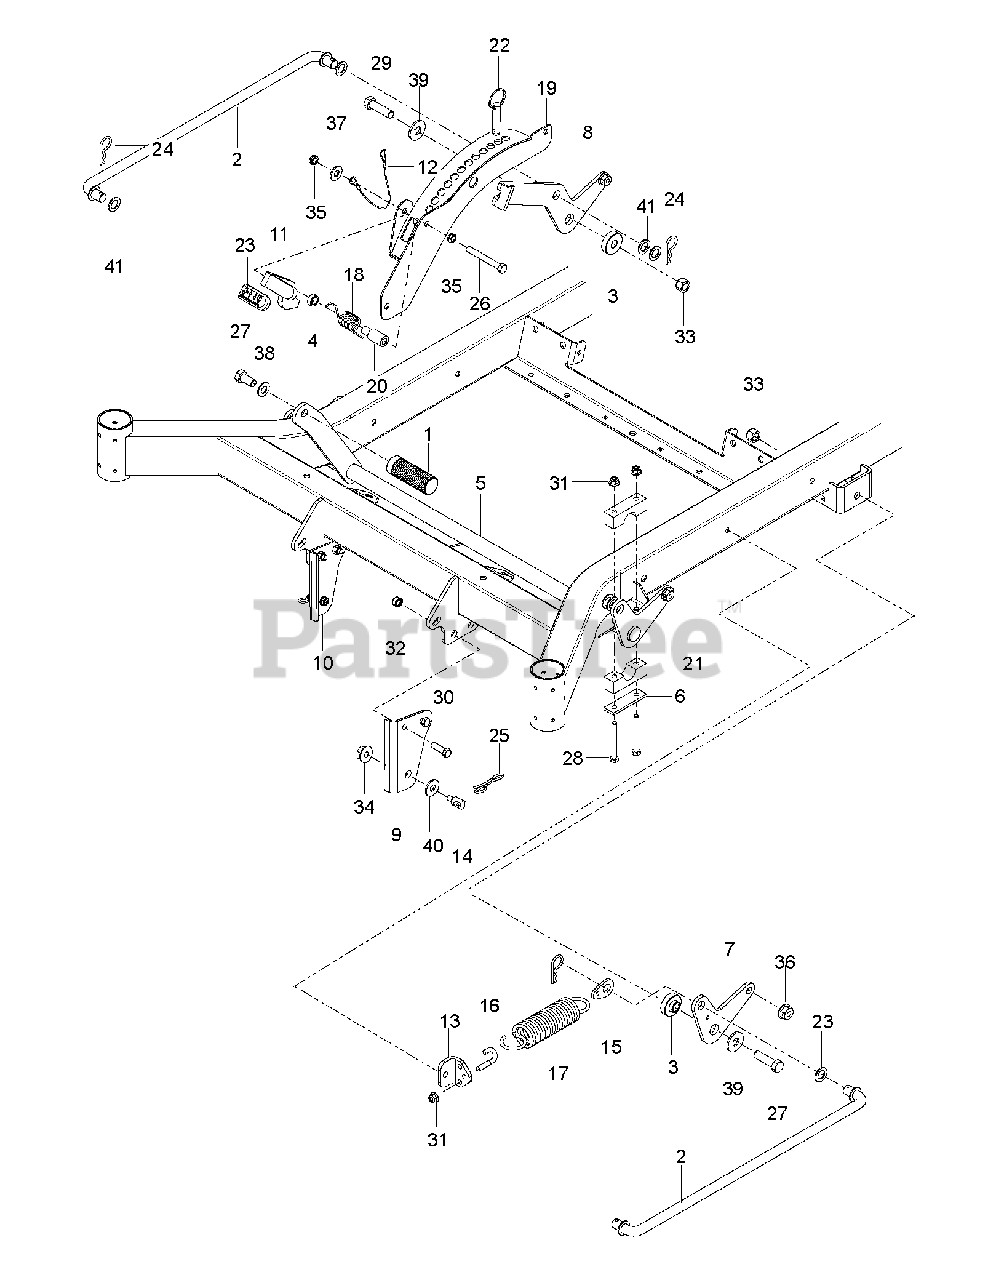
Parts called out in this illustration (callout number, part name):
1	PEDAL, DECK HEIGHT
2	CROSS LINK
3	SPACER.IDLER.METAL.POWDER
4	SPACER, .3
5	LIFT.PNT.MZ.DECK.WELD.E-DIP
6	REINFORCEMENT.PLATEX431
7	BELLCRANK, RR, LIFT
8	BELLCRANK, RR, RT
9	BRACKET.PNT.SUSP.CHAS.FR.LH.OR
10	BRACKET.PNT.SUSP.CHAS.FR.RH.OR
11	LATCH, TRANSPORT
13	MOUNT, SPRING
14	STUD.FASTNER.W/ANTI-ROTATE
15	TAB, SPRING
18	SPRING, TORSION
19	HEIGHT, ADJUST, DECK
20	PIVOT, LATCH, TRANSPORT
21	PILLOW BLOCK
22	PIN, 1/2 X 1 1/2, DETENT RING
23	GRIP, TRANSPORT-RELEASE
24	PIN, COTTER 1 3/4
25	PIN.COTTER.7/16.BOW TI.
26	BOLT.HEX.FIN.3/8-16 X 3.GR5
27	HHCS 1/2-13 X 1
29	HCS 1/2-13 X 1 3/4 GR 8
30	HCS 3/8-16X1.GRD.5.ZD
31	5/16-18 NYLOC FLANGE NUT
32	NUT 3/8-16 NYLOC
33	NUT.LK.W/WSH.1/2.
34	NUT LOCK HEX FLANGE 5/16-18
35	NUT HEX 3/8-16 NYLON, THIN
36	NUT LOCK FLG 3/8-16 UNC
37	WASHER 3/8 FLAT
38	CONTACT BELLSPR 1/2
39	WASH USS FLAT 1/2
40	WASHER.CLEAR.ZINC
